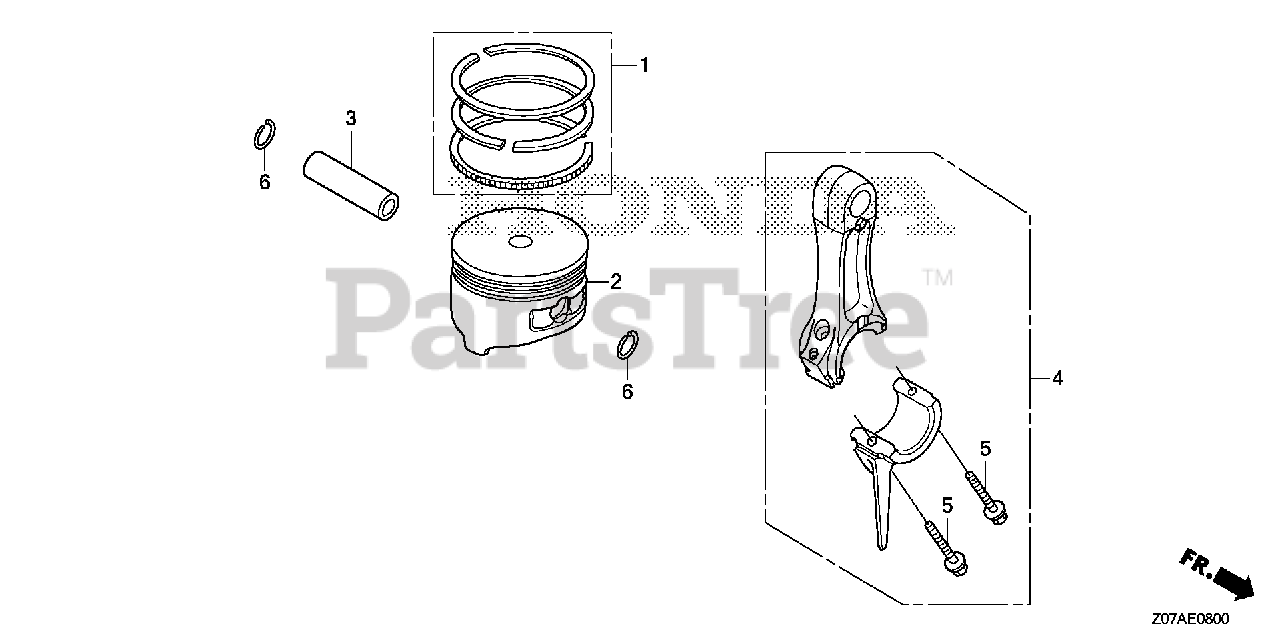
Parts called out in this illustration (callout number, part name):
1	RING SET, PISTON
3	PIN, PISTON
4	ROD ASSY., CONNECTING
4	ROD ASSY., CONNECTING (UNDER SIZE)
5	BOLT, CONNECTING ROD
6	CLIP, PISTON PIN (13MM)
